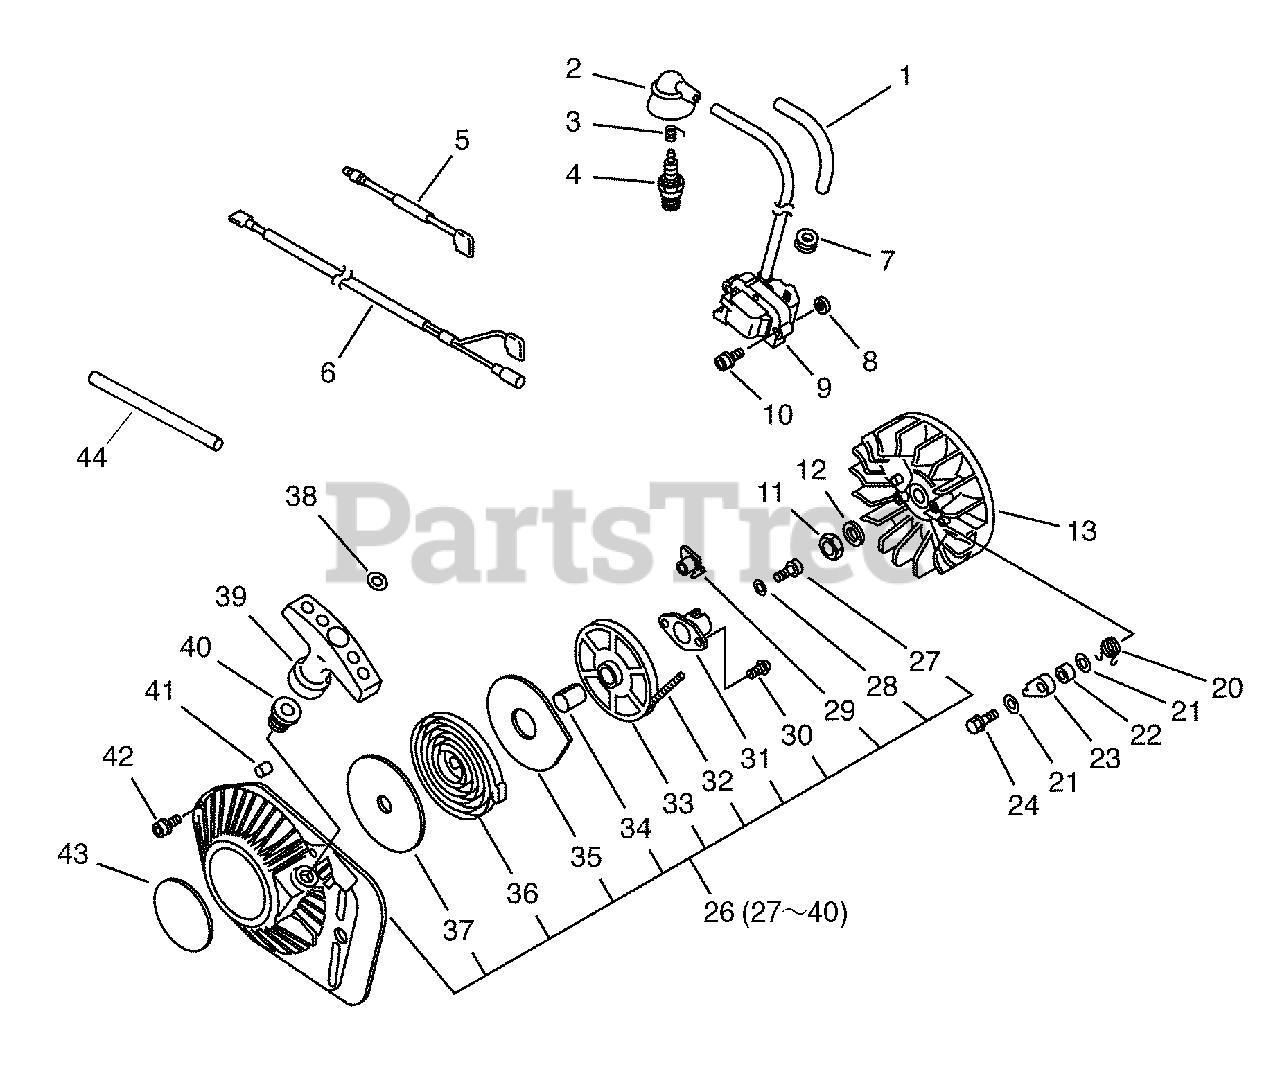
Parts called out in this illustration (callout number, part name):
1	TUBE, PROTECTIVE
2	CAP, SPARK PLUG
3	TERMINAL, SPARK PLUG CAP
4	SPARK PLUG -- CJ-6Y
5	LEAD - IGNITION
6	LEAD - GROUND
9	COIL, IGNITION
10	SCREW - 5X25
13	FLYWHEEL
20	SPRING, RETURN
21	WASHER - 6
23	PAWL, STARTER
24	BOLT - 6X16
26	STARTER ASSY
27	BOLT - 5X14
29	RETAINER, ROPE
30	SCREW - 4X12
31	CATCHER, PAWL
32	ROPE, STARTER
33	REEL, ROPE
35	PLATE, STARTER
36	SPRING, REWIND
37	PLATE, STARTER
38	WASHER
39	GRIP, STARTER
40	GUIDE, ROPE
41	PIN - LOCATING
42	SCREW - 6X25
43	LABEL - ECHO
